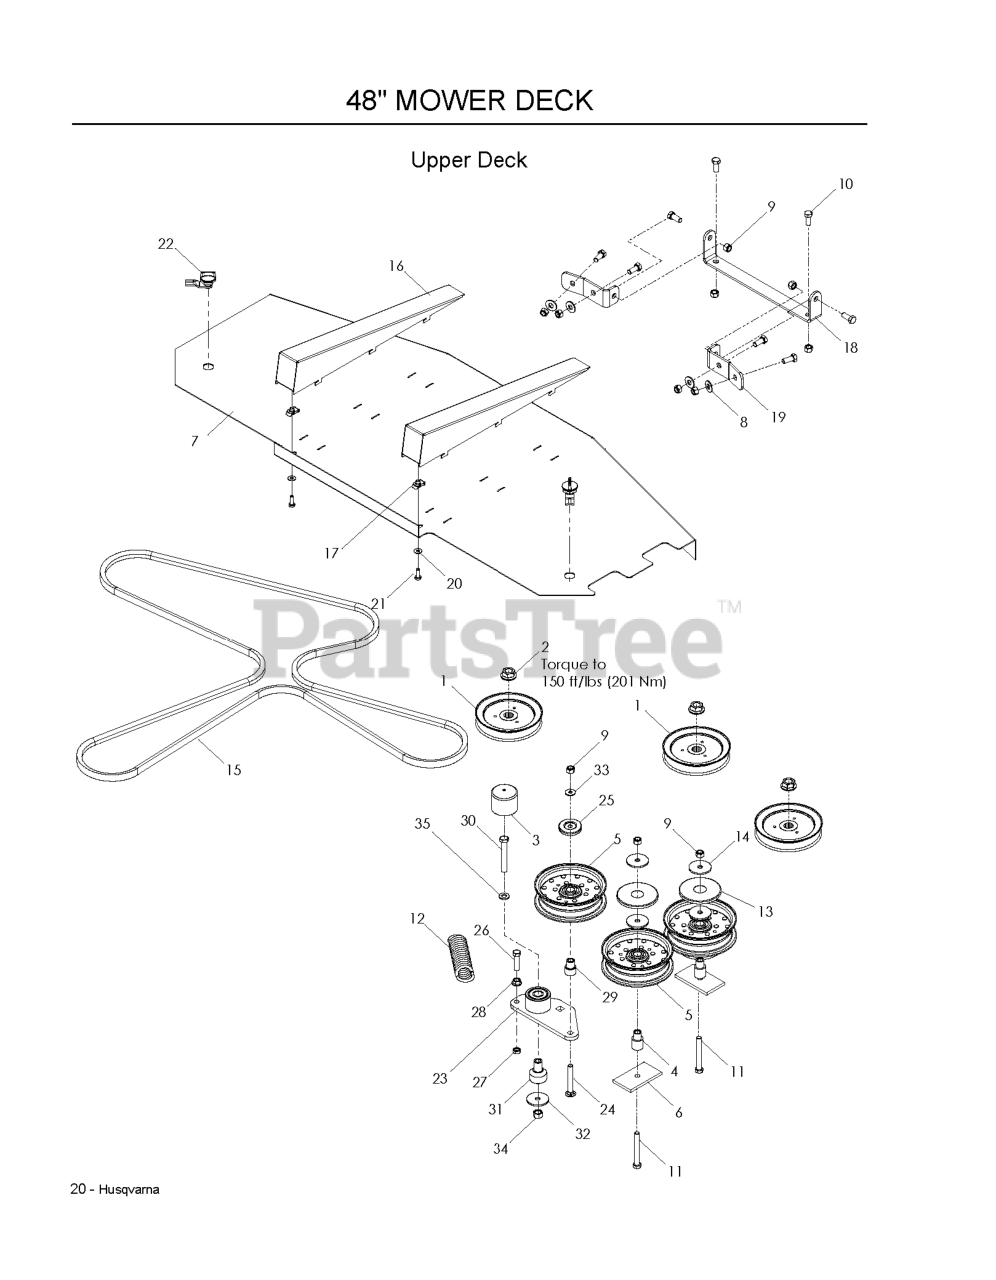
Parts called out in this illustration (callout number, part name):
1	PULLEY - 5.25
2	NUT FLANGE 3/4-16
3	CAP, VINYL
4	IDLER BUSHING
5	IDLER PULLEY
6	SUPPORT PLATE
7	COVER - BELT, 48 PAINTED
8	WASHER 3/8 FLAT
9	NUT 3/8-16 NYLOC
10	HCS 3/8-16 X 7/8 GR 5 ZD
11	HCS 3/8C X 3
13	TOP DUST CAP
14	WASHER, 3/8 SPEC
16	WEDGE - PAINTED
17	1/4C - U TYPE RETAINER
18	HINGE, BIN
19	BASE HINGE - PAINTED
20	WASHER 1/4 SAE
21	HCS 1/4C X 3/4 HCS
22	LATCH, SHORT WING
23	ARM-IDLER W/BRG
24	RHSNB 3/8-16 X 2.75
25	DUST SHIELD
26	HCS 3/8-16 X 1-1/2
27	NUT 3/8-16 HEX JAM
28	NUT 3/8C WHIZ
29	BUSHING, IDLER
30	HCS 1/2C X 3 1/4
31	PIVOT, BEARING
32	WASHER, SUPPORT
33	WASHER, 3/8 THICK
34	NUT 1/2-13 HEX NYLOC ZD
35	CONTACT BELLSPR 1/2
